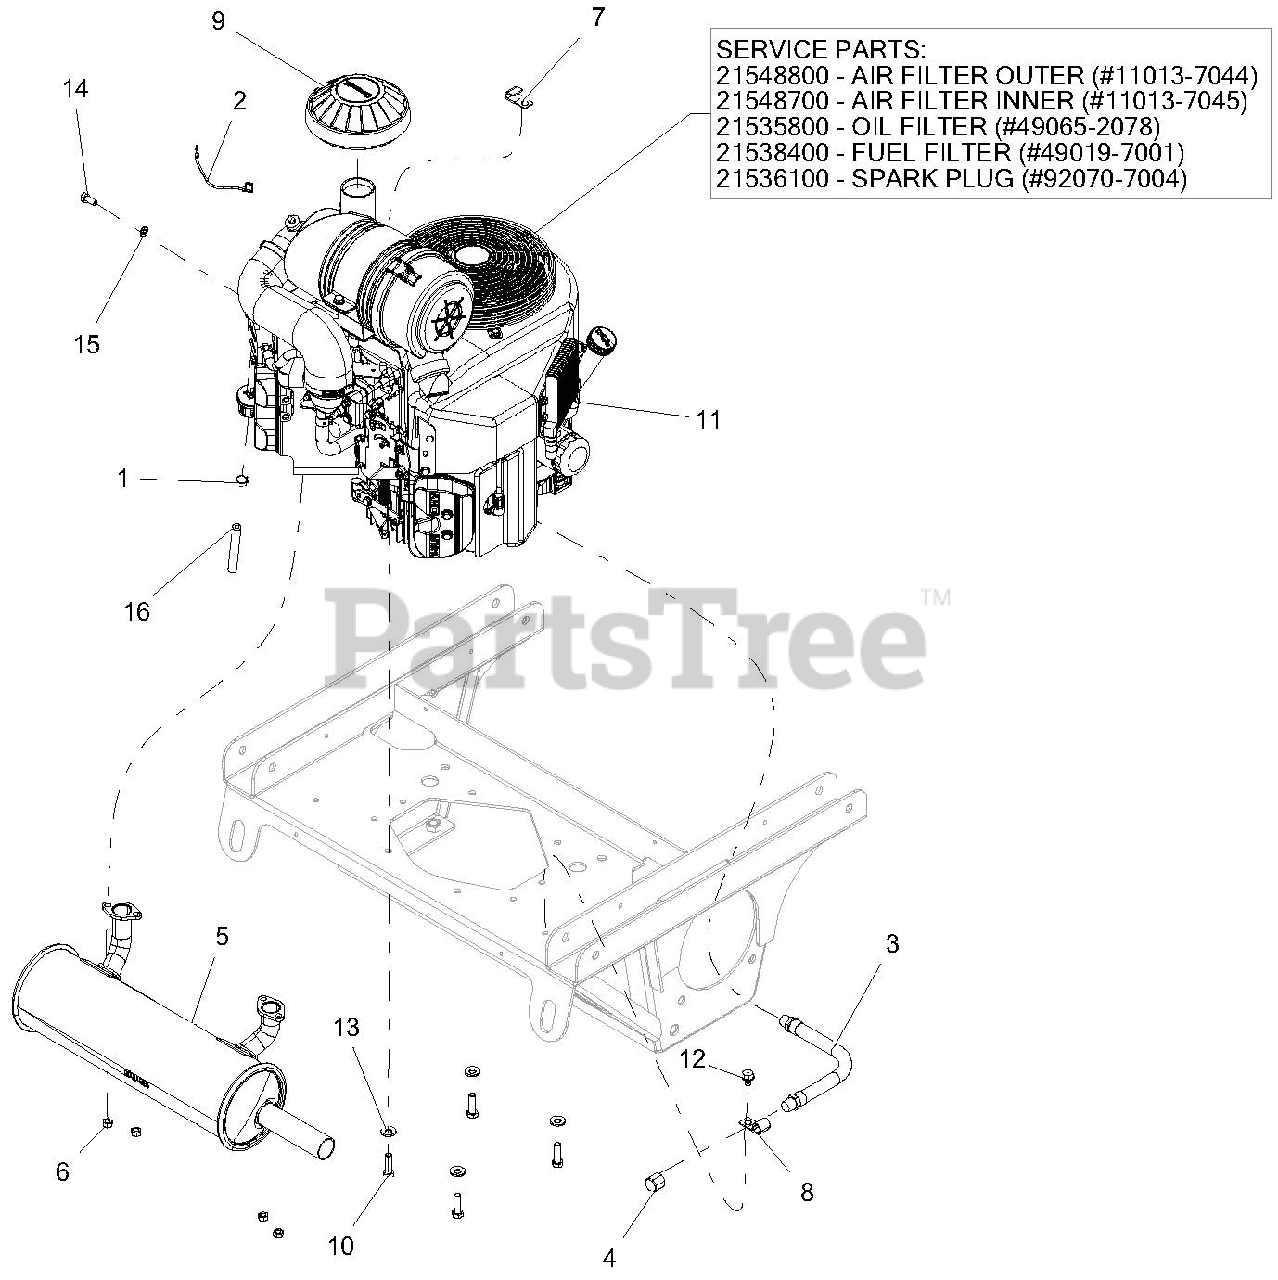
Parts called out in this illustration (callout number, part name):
1	CLAMP, FUEL LINE
2	LEAD - STARTER SOLENOID
3	HOSE, HYD .38-11-0K M6N0-M6NO
4	PIPE, CAP 3/8 NPT FEMALE
5	MUFFLER, 27-31 FX KAW
6	NUT-LK-TOP M8-1.25 YWZC
7	CLAMP, J
9	CAP, AIR CLEANER INTAKE
10	BLT-HEX .38-16X1.25 GR5 YWZC NYTORQ
11	ENGINE, KAWASAKI FX850
11	AIR FILTER OUTER (#11013-7044)
11	AIR FILTER INNER (#11013-7045)
11	OIL FILTER (#49065-2078)
11	FUEL FILTER (#49019-7001)
11	SPARK PLUG (#92070-7004)
12	SCR-TAP .38-16X.50 HWH TR YWZ
13	WSHR, 3/8" SPRING DISC
14	@BLT-HEX M8-1.25X20 YWZC
15	WSHR-LK .31X.078 REG YWZC
16	.25 LOW-PERM GAS HOSE 28.00" LG
